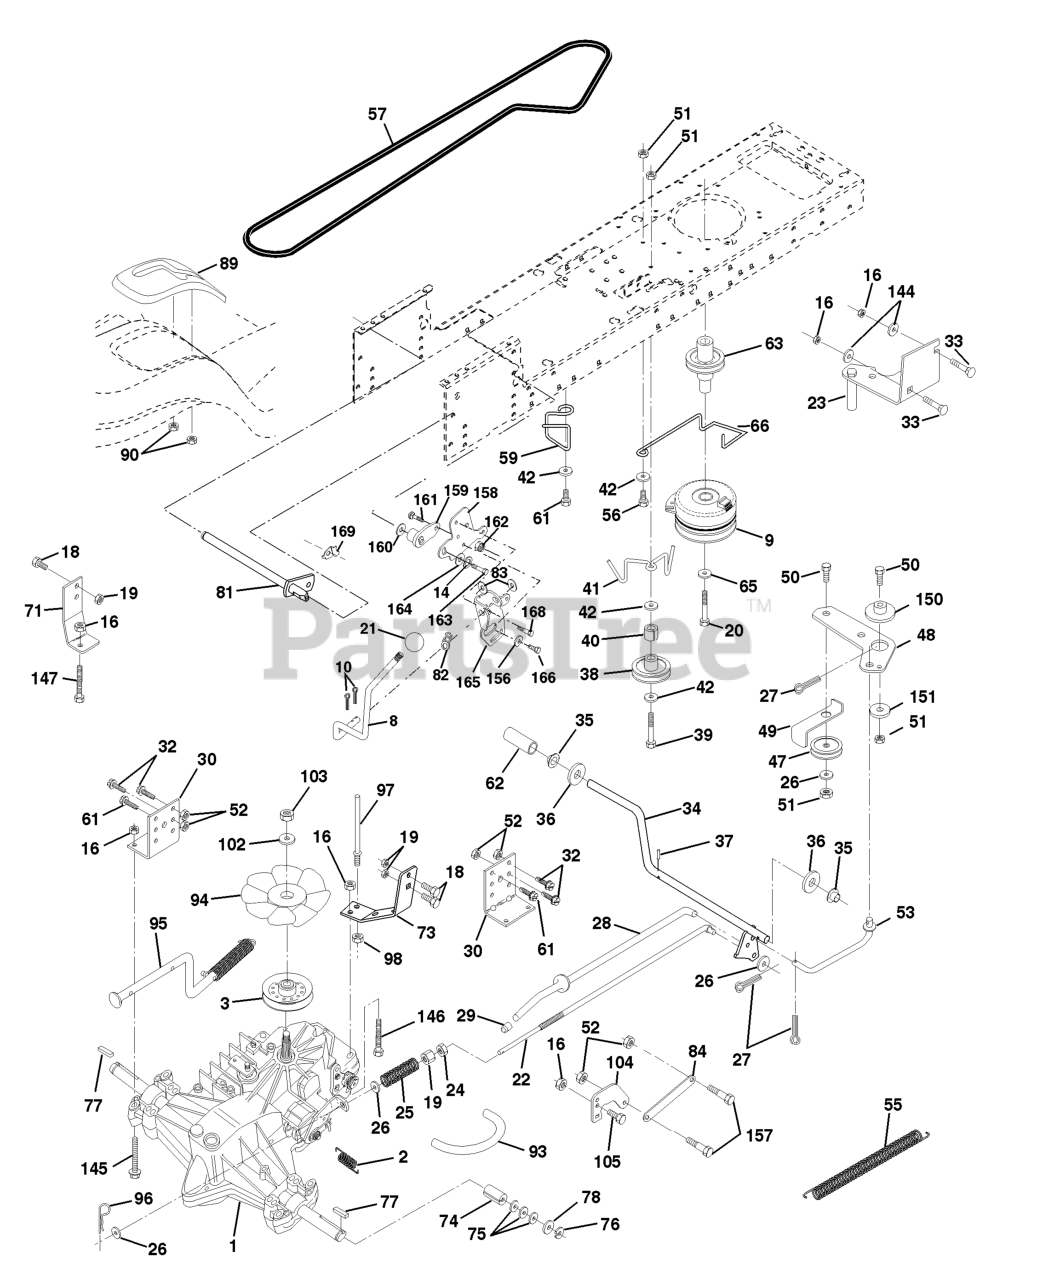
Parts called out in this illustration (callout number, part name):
1	TRANSAXLE ASSEMBLY
2	SPRING BRAKE
3	PULLEY, TRANSAXLE
8	ROD SHIFT FENDER
9	ELECTRIC CLUTCH
10	PIN COTTER
16	NUT.71038.31-18.HEX.NYLOCK
18	BOLT
19	NUT
20	BOLT HEX
21	KNOB.DELUXE.(PISTOL.GRIP).BLAC
22	ROD BRAKE HYDRO
23	BRACKET, ASM CLUTCH MTG
24	NUT
25	SPRING ROD LT
26	WASHER
27	COTTER PIN
28	ROD BRAKE PARK LT
29	PLUNGER CAP
30	BRACKET TRANSAXLE
32	BOLT
33	RP BOLT 5/16-18 X3/4 ZN/YEL GR
34	SHAFT, FOOT PEDAL
35	BEARING.NYLON
36	WASHER LT
37	DRIVE PIN
38	PULLEY.IDLER.FLAT
41	KEEPER, BELT IDLER
42	WASHER
47	IDLER PULLEY
48	BELLCRANK, CLUTCH
49	RETAIN BELT
50	BOLT
52	LOCKNUT
53	LINK, CLUTCH LT
55	SPRING, RETURN LT
57	DRIVE BELT, LTH & YTH TRACTORS
59	KEEPER CENTER SPAN
61	SCREW
62	COVER, PEDAL (1 2)
63	PULLEY, CLUTCH ELECT EVX
65	LOCKWASHER
66	KEEPER BELT ENGINE
71	STRAP LH TORQUE
73	STRAP TORQUE RH HYDRO
74	SPACER SPLIT
77	SQUARE KEY
81	SHAFT ASSY
82	SPRING,TORSION
83	WASHER
89	SHIFT CONSOLE
90	NUT.PUSH.3/16
93	LINE FUEL HYD 4"
94	FAN 7" HYDRO
95	CONTROL ARM, BYPASS HYDRO
96	RETAINER M
97	KEEPER BELT RH
100	WASHER M
103	NUT.HEX.1/2-20
104	CONTROL ARM
106	BOLT.5/16-18X1-1/4 FULL.THREAD
144	Washer 11/32 x 5/8 x 16 Ga.
145	BOLT
146	Bolt Hex Flghd 5/16-18 x 2-1/4
147	Bolt Hex Flghd 5/16-18 x 1-1/2
149	SPACER RETAINER
150	BUSHING NYLON COLLERED
151	WASHER 12/32X2X10GA
